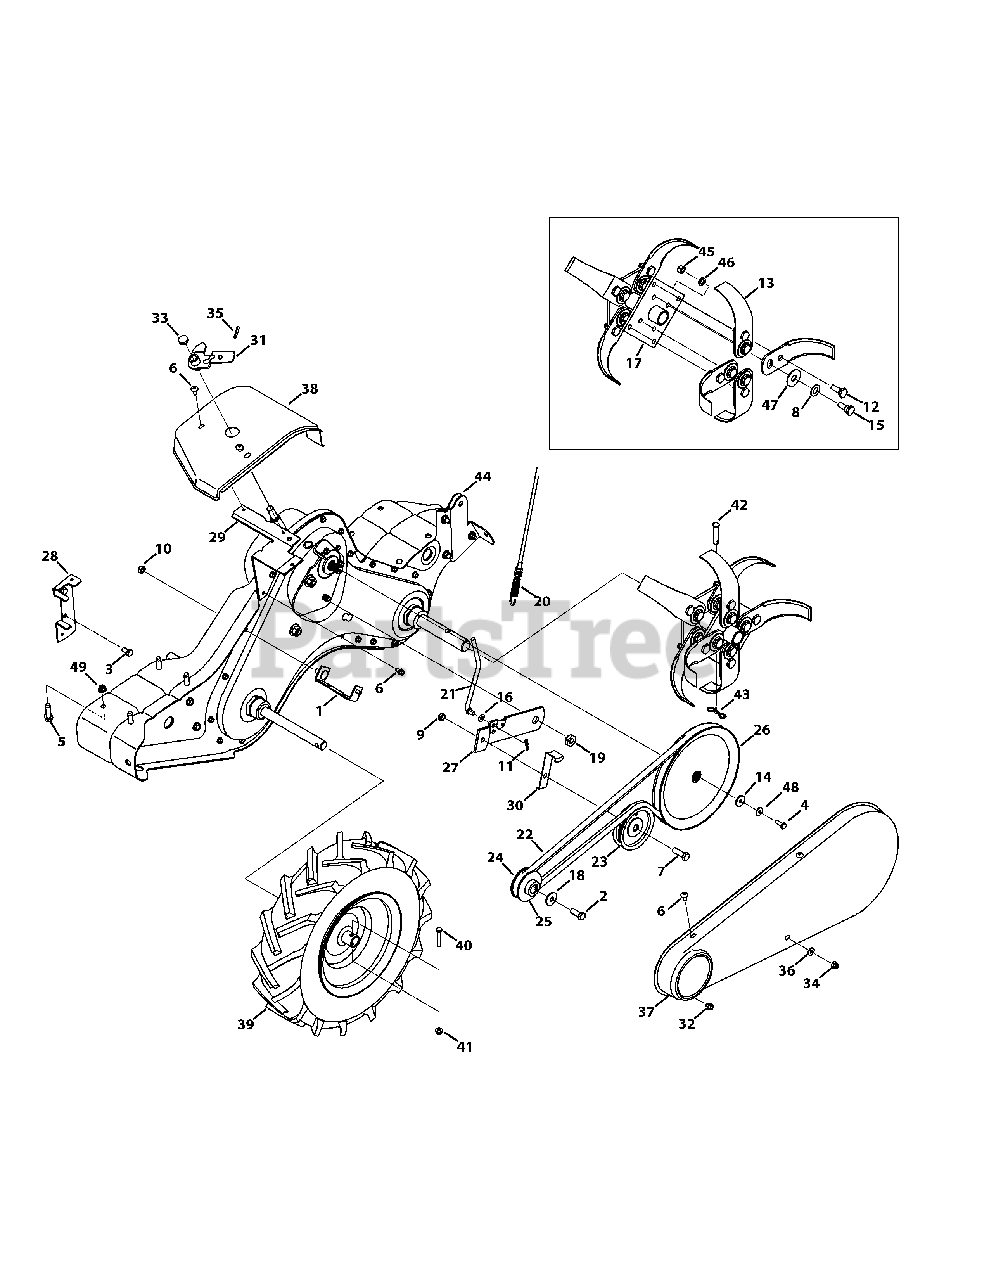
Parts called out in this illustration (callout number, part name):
1	Belt Cover Bracket Assembly
2	Hex Head Screw, 3/8-24 x 100
3	Hex Bolt, 5/16-24 x 625
4	Hex Bolt, 1/4-28 x 75"
5	Hex Screw, 3/8-16 x 150" (Honda)
6	Hex Washer Screw
7	Hex Head Screw, 3/8-16 x 125
8	Washer, Bell, 525 x 100 x 050
9	Jamlock Nut, 3/8-16
10	Flangelock Nut, 5/16-18
11	Cotter Pin, 072 DIA x 113 LG
12	Screw, Shoulder, 3/8-24 x 1/2 x 180
13	Articulating Tine
14	Washer, Flat, 265 x 938 x 120
15	Screw, Shoulder, 3/8-24 x 1/2 x 325
16	Washer, Spring, 317 x 625 x 020
17	Tine Adaptor Assembly
18	Washer, Bell, 396 x 1140 x 095
19	Shoulder Nut, 7/16-20
20	Clutch Cable
21	Idler Pulley Rod
22	Belt, 4L x 5816 LG
23	Flat Idler Pulley w/ Flanges, 375 OD
24	Engine Pulley, Inner Half
25	Engine Pulley, Outer Half
26	Input Pulley, 4L x 8594
27	Idler Pulley Bracket
28	Belt Keeper Bracket, B&S 65 HP
29	Shift Cover Bracket
30	Idler Belt Keeper
31	Shift Crank Assembly
32	Screw, 1/4-20:0375
34	Lock Nut, Cap, 1/4-28
35	Spiral Pin, 3/16 x 100
36	Washer, Flat, 271x 630 x 065
37	Belt Cover
38	Shift Cover
39	Wheel, 16 x 46 x 8
40	Hex Head Screw, 1/4-20 x 150
41	Flangelock Nut, 1/4-20
42	Clevis Pin, 375 x 175
43	Cotter Pin, Bow-Tie
44	Complete Gear Case Assembly
45	Hexlock Nut, 3/8-24
46	Washer, Lock, 3/8
47	Washer, Flat, 51 x 15 x 007
48	Bell Washer, 265 x 750 x 060
49	Flangelock Nut, 3/8-16 (Honda)
